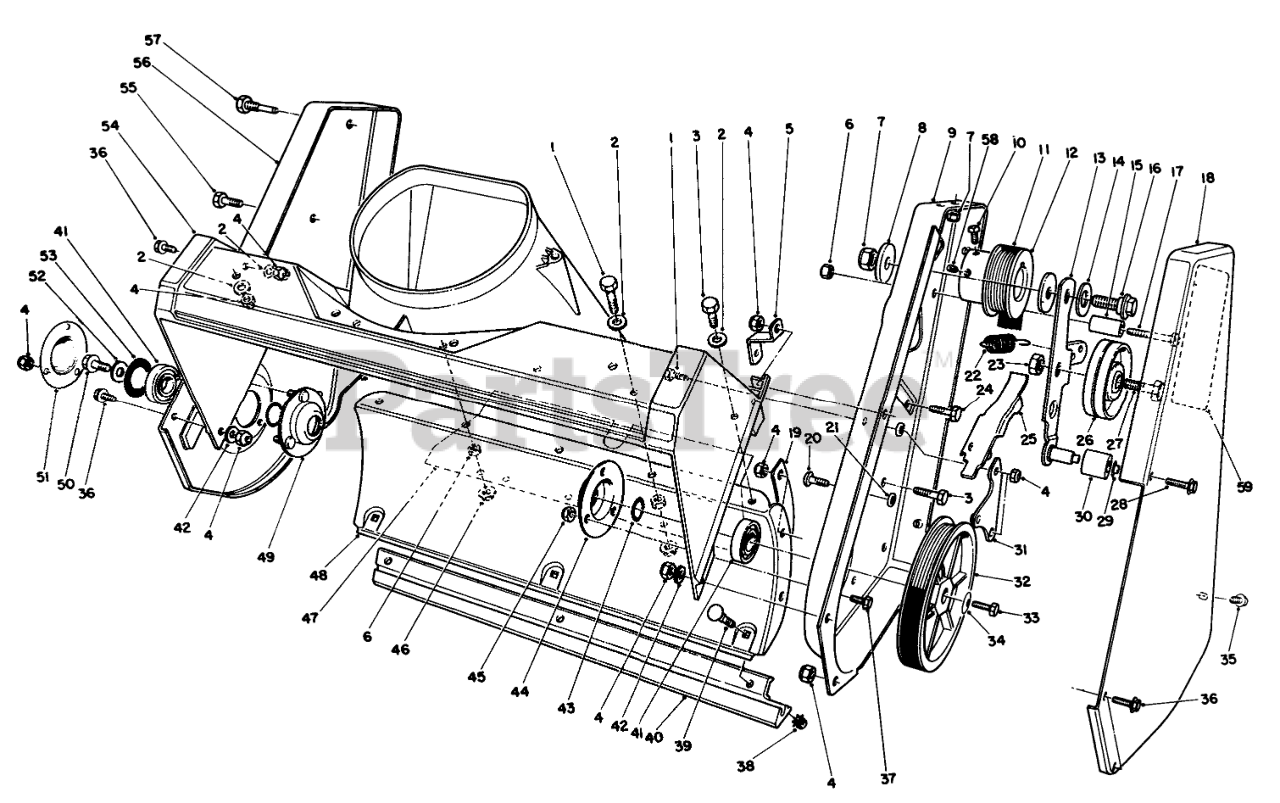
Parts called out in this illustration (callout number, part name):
1	SCREW-HH
2	WASHER-FLAT
3	SCREW-HH
4	NUT-LOCK, NI
5	BRACKET-HOUSING
6	NUT-HEX, SIDE DEFORM
7	NUT-LOCK, NI
8	WASHER-PIVOT
9	Sideplate-L.H.
10	SCREW-SQH
11	BELT - DRIVE
12	ENGINE PULLEY
13	Idler Arm Assembly (Incl. Ref. #29 & 30)
14	WASHER
15	SLEEVE-GUIDE, BELT
16	SCREW-SHOULDER
17	SCREW-HH
18	Cover-Drive
19	BRACKET-HOUSING, LOWER
20	SCREW-HSBH
21	SPACER-PLATE, PIVOT
22	SPRING-EXTENSION
23	NUT-LOCK, CONE
24	SCREW-HH
25	BRAKE-ARM
26	PULLEY-IDLER
27	SCREW-HH
28	SCREW-HWH, TAP
29	NUT-PUSH
30	ROLLER-BRAKE
31	PIVOT PLATE ASM
32	ROTOR PULLEY ASY
33	SCREW-HH
34	WASHER-BELLEVILLE
35	SCREW
36	SCREW-HWH
37	SCREW-SHH
38	NUT-KEPS
39	SCREW-CARR
40	SCRAPER
41	BEARING-BALL
42	WASHER-FLAT
43	WASHER-THRUST
44	FLANGE-BEARING
45	NUT-LOCK, NI
46	NUT-LOCK, HHF
47	BOTTOM COVER
48	Housing-Lower
49	FLANGE-BEARING
50	SCREW-HHF
51	Trough
52	WASHER-FLAT
53	WASHER-RUBBER
54	HOUSING
55	SCREW-HH
56	Sideplate-RH
57	PIN-ROTOR
58	SCREW-HSH
59	DECAL
